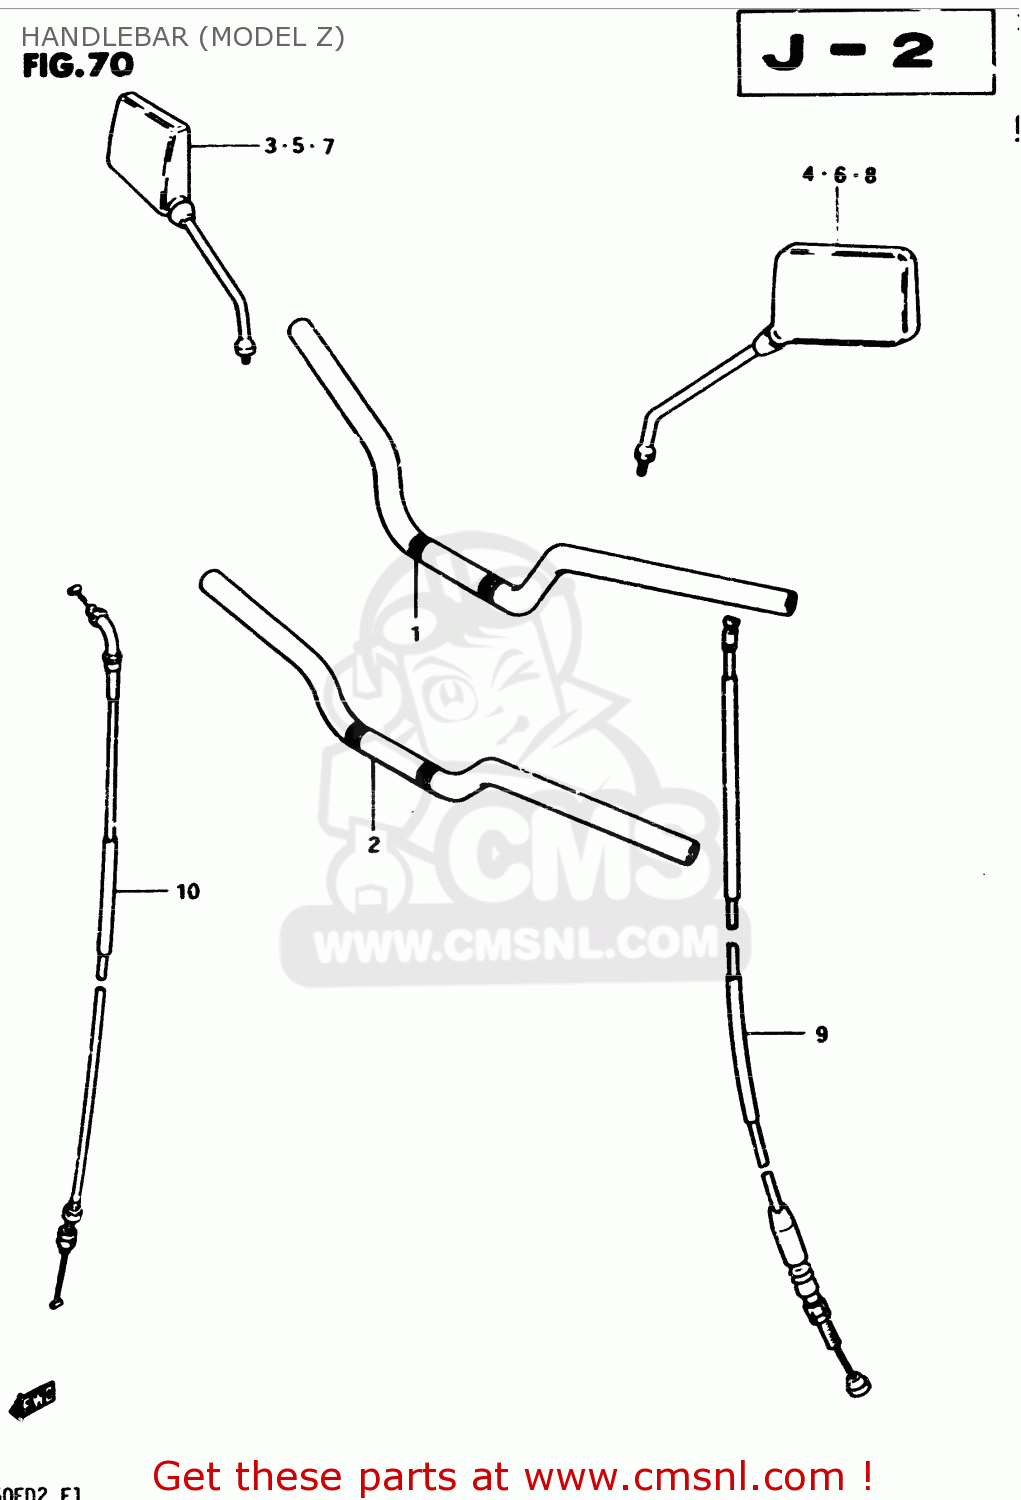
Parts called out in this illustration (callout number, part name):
1	HANDLEBAR
2	HANDLEBAR (FLAT HANDLEBAR)
3	MIRROR ASSEMBLY,REAR VIEW
4	MIRROR ASSEMBLY,REAR VIEW
5	MIRROR, REAR VIEW RH
6	MIRROR, REAR VIEW LH
7	MIRROR, REAR VIEW RH
8	MIRROR, REAR VIEW LH
9	CABLE ASSY,CLUTCH
10	CABLE ASSEMBLY,THROTTLE
